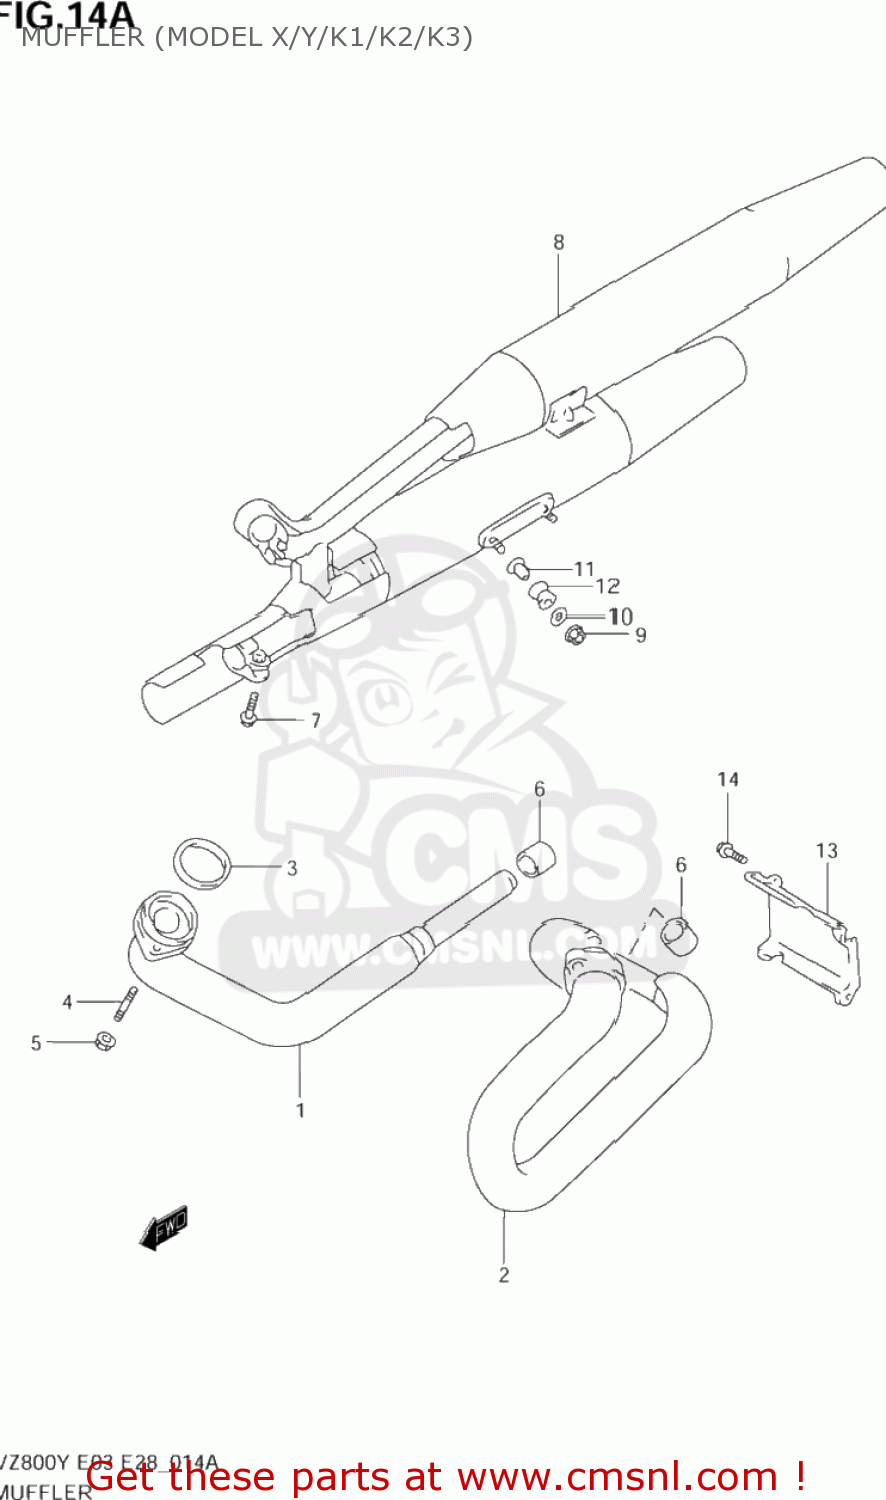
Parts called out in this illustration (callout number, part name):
1	PIPE,EXHAUST,R
2	PIPE,EXHAUST,L
3	GASKET,EXHAUST PIPE (NAS)
4	BOLT,STUD
5	NUT
6	CONNECTOR,MUFFLER JOINT
7	BOLT(8X33)
8	MUFFLER
9	NUT
10	WASHER (8.5X26X1.6)
11	SPACER(8.6X12X17.5)
12	CUSHION
13	GUARD,HEAT
14	BOLT
